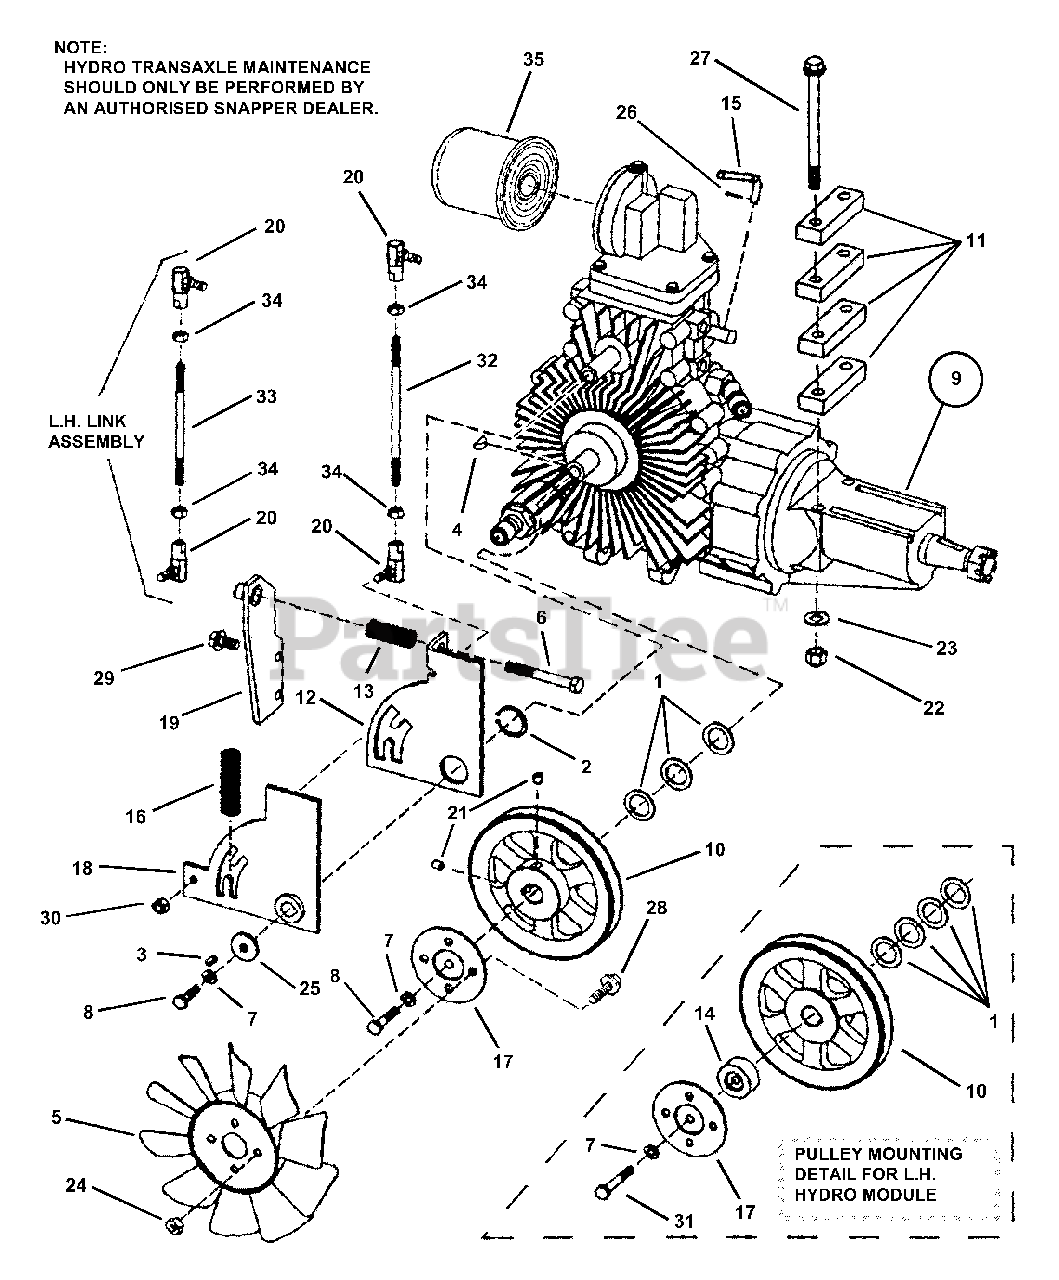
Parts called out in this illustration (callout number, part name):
1	WASHER, 3/4 I.D. x 1-1/8" O.D. Flat
2	RETAINING RING, 1" External
3	WOODRUFF KEY, #404
4	WOODRUFF KEY, #605
5	FAN, 10 Blade 7" Dia.
6	BOLT, 5/16-18 X 2-1/2" GD5 YZ
7	WASHER, 1/4 Split Lock
8	SCREW, 1/4-20 x 1-1/4", Hex Head Cap
9	ASSEMBLY, Transaxle 771-108 (R.H.) Side
10	PULLEY, Transmission Input
11	SPACER, Eaton Transaxle
12	PLATE, Neutral Adjust
13	SPRING, Neutral Return Adjust
14	SPACER/ADAPTER, Fan
15	ROD, Roll Release
16	SPRING, Neutral Return
17	SPACER, Fan (Weldment)
18	CAM, Neutral Return (Weldment)
19	PLATE, Neutral Return (Weldment)
20	BALL-JOINT
21	SET SCREW, 5/16-18 x 5/8" Hex Recess
22	NUT, 3/8-16 HEX NYLON LOCK
23	WASHER, 3/8" Flat
24	NUT, 1/4-20 HEX NYLON LOCK
25	WASHER, 1/4 I.D. x 1" O.D.
26	COTTER-PIN, 1/16 x 1/2"
27	BOLT, 3/8-16 x 4-3/4" Grade 5
28	SCREW, 1/4-20 x 5/8", Hex Flange Lock, Grade 5
29	BOLT, 5/16-18 x 5/8", Hex Flange Lock
30	NUT, 1/4-28, Hex Nyloc
31	SCREW, 1/4-20 x 2", Hex Head Cap, Grade 5
32	ROD, Threaded 1/4-28 x 5-3/8"
33	ROD, Threaded 1/4-28 x 4-3/8"
34	NUT, 1/4-28 Hex, Grade 5 or B
35	FILTER, Oil
